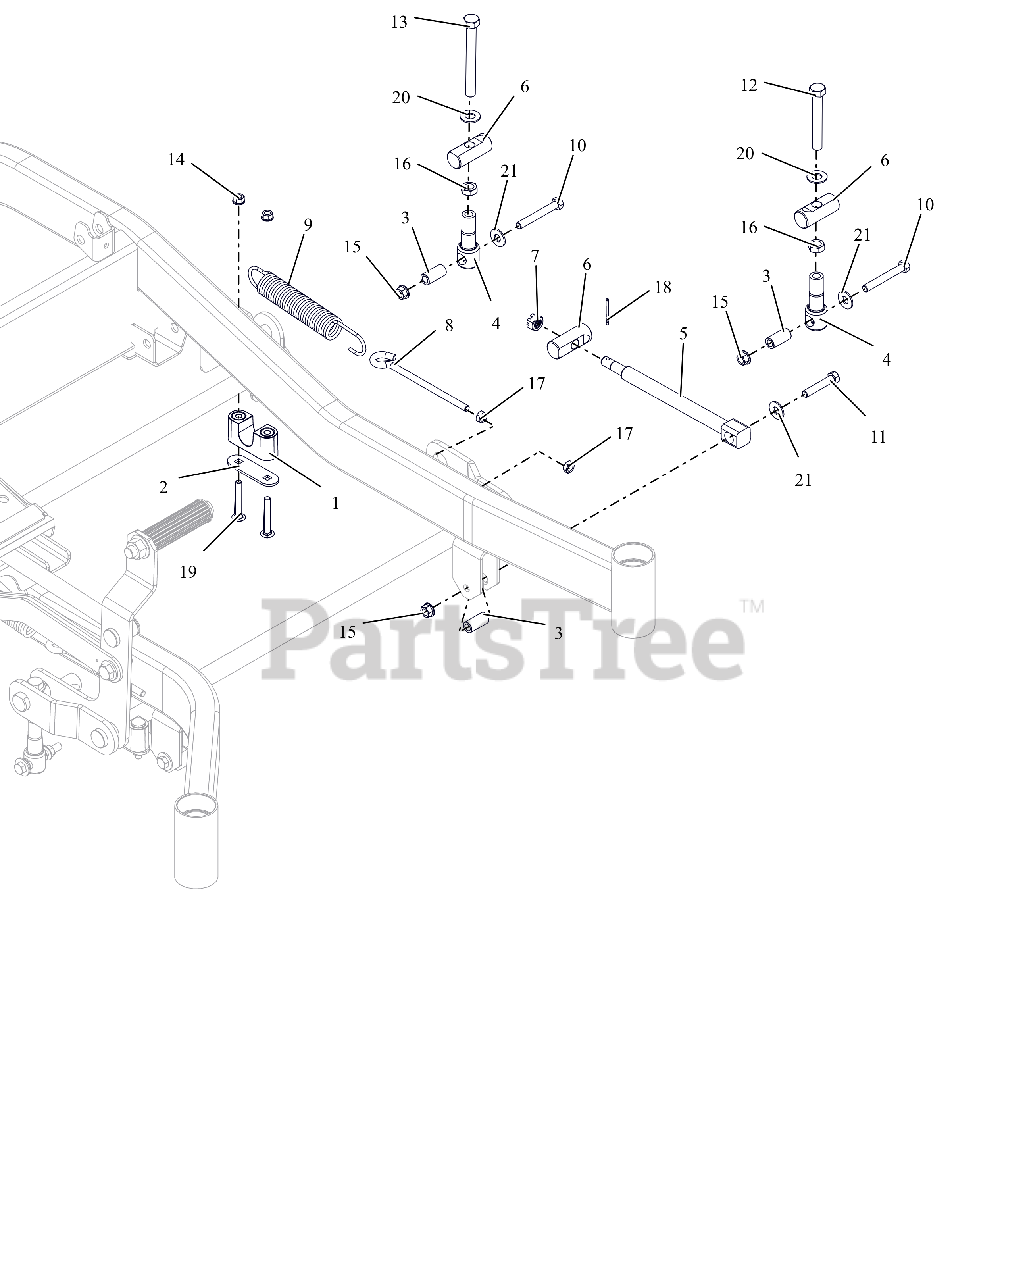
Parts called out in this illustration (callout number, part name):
1	ASM-BUSHING, DECK LIFT
2	PLATE, BEARING SUPPORT
3	SPACER, DECK LEVELING
4	LINK, DECK LIFT FORMED
5	DRAG,LINK-HD
6	PIN, DECK LIFT
7	NUT-SL .50-13
8	BOLT,.38-16 X 5.25-.62 DIA EYE
9	SG-TENS .162X1.25X8.25 WLD 25
10	BLT, HEX .38-16X2.75 G8 ZCC
11	BLT,HEX .38-16X2.00 G5 ZCC
12	BLT, HEX 0.5-13X3.5F GR5 ZCC
13	BLT, HEX .50-13X4.50F G8 ZCC
14	NUT,LK-CTR-FLG .31-18 GF ZCC
15	NUT-LK-TOP-FLG .38-16 ZC120
16	NUT-JAM .500-13 G2 ZCC
17	NUT-JAM .375-16 G2 ZCC
18	PIN,CTR.12X1.25EXTPRSQCT ZC120
19	BLT, RHSSN.31-18X2.25 G5 ZCC
20	WSHR, FLT .557X1.040X.102 ZCC
21	WSHR,FLT .438X1.00X.083 ZCC
